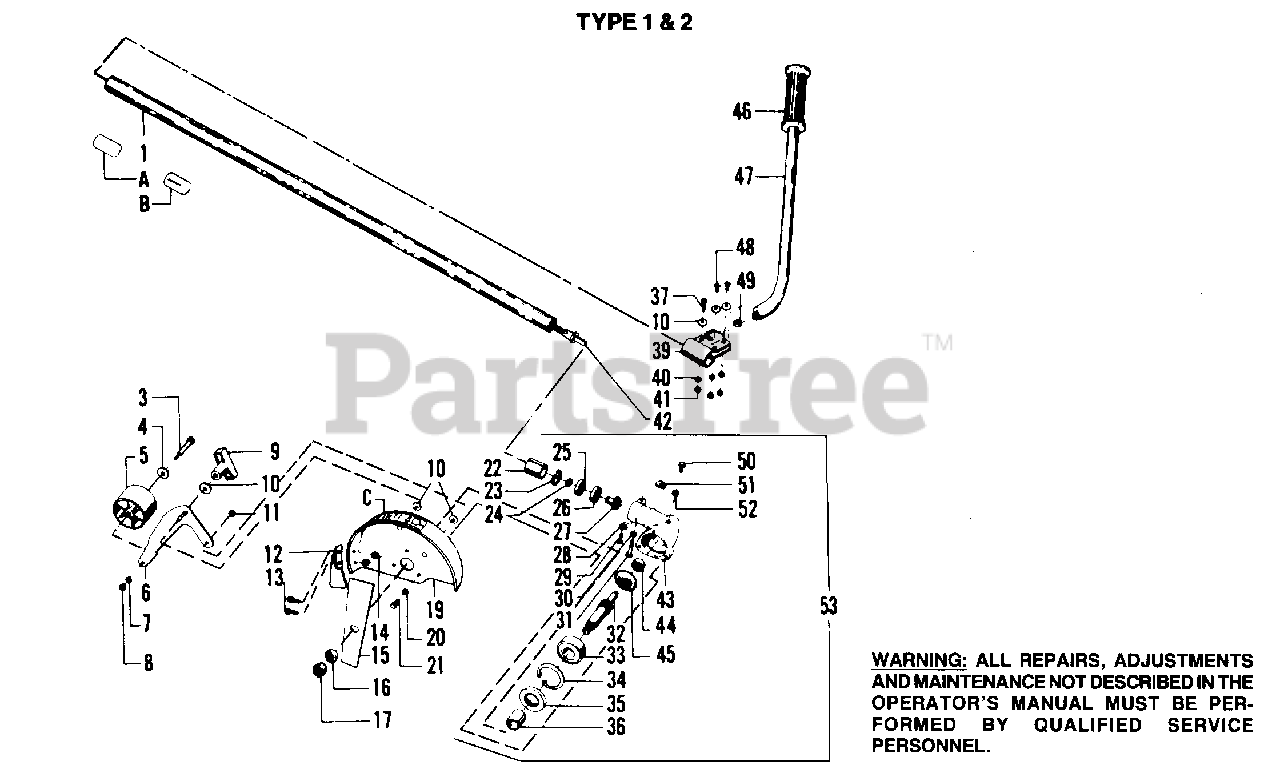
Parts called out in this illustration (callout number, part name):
1	Drive Shaft Housing Assembly
3	Shoulder Bolt - Wheel - #5/16 - 18 x 5/64"
4	Washer - Wheel
5	Wheel - Depth Adjusting
6	Bracket - Wheel
7	Lockwasher - Wheel to Bracket
8	Nut - Bracket to Guard - #5/16 - 18"- Hex
9	Knob - Wheel
10	Washer - #1/4 - Flat
11	Locknut - Bracket to Guard - #1/4 - 20"
12	Edge Guide
13	Screw - Edge Guide - #10 - 24 x 7/16"
14	Nut - Edge Guide - #10 - 24" - Locknut
16	Lockwasher - Blade Mounting
17	Nut - #7/16 - 14" - Blade Mounting
19	Guard Assembly
20	Lockwasher - Guard to Gear Housing
21	Screw - Guard to Gear Housing - #1/4 - 20 x 1/2"
22	Sleeve - Drive Shaft Tube
23	Retaining Ring
24	Retaining Ring - Pinion
25	Bearing - Sealed
26	Bearing - Open
27	Gear - Pinion
28	Lockwasher - Index Screw
29	Screw - Index - #10 - 24 x 1/2"
30	Lockwasher - Pinch Clamp
31	Screw - Pinch Clamp - #1/4 - 20 x 1-3/16"
32	Shaft - Output
33	Bearing - Large
34	Retaining Ring
35	Seal - Oil
36	Collar - Shaft
37	Screw - Clamp - #1/4 - 20 x 5/8"
39	Clamp - Handlebar
40	Lockwasher - Clamp
41	Nut - Handlebar - #1/4 - 20 - Hex
42	Drive Shaft Assembly
43	Gear Housing
44	Bearing - Small
46	Grip - Handlebar
47	Handlebar
48	Screw - #1/4 - 20 x 1" - Handlebar
49	Spacer - Handlebar
50	Screw - Lubrication Filler - #5/16 - 18 x 3/8"
51	Spacer - Fiber - Pinch Clamp
52	Washer - Fiber
53	Gear Housing Assembly (Incl. #'s 22 - 36, 43, 44, 45 & 50 - 52)
A	Decal - Product
B	Decal - Handlebar Location
C	Decal - Guard
